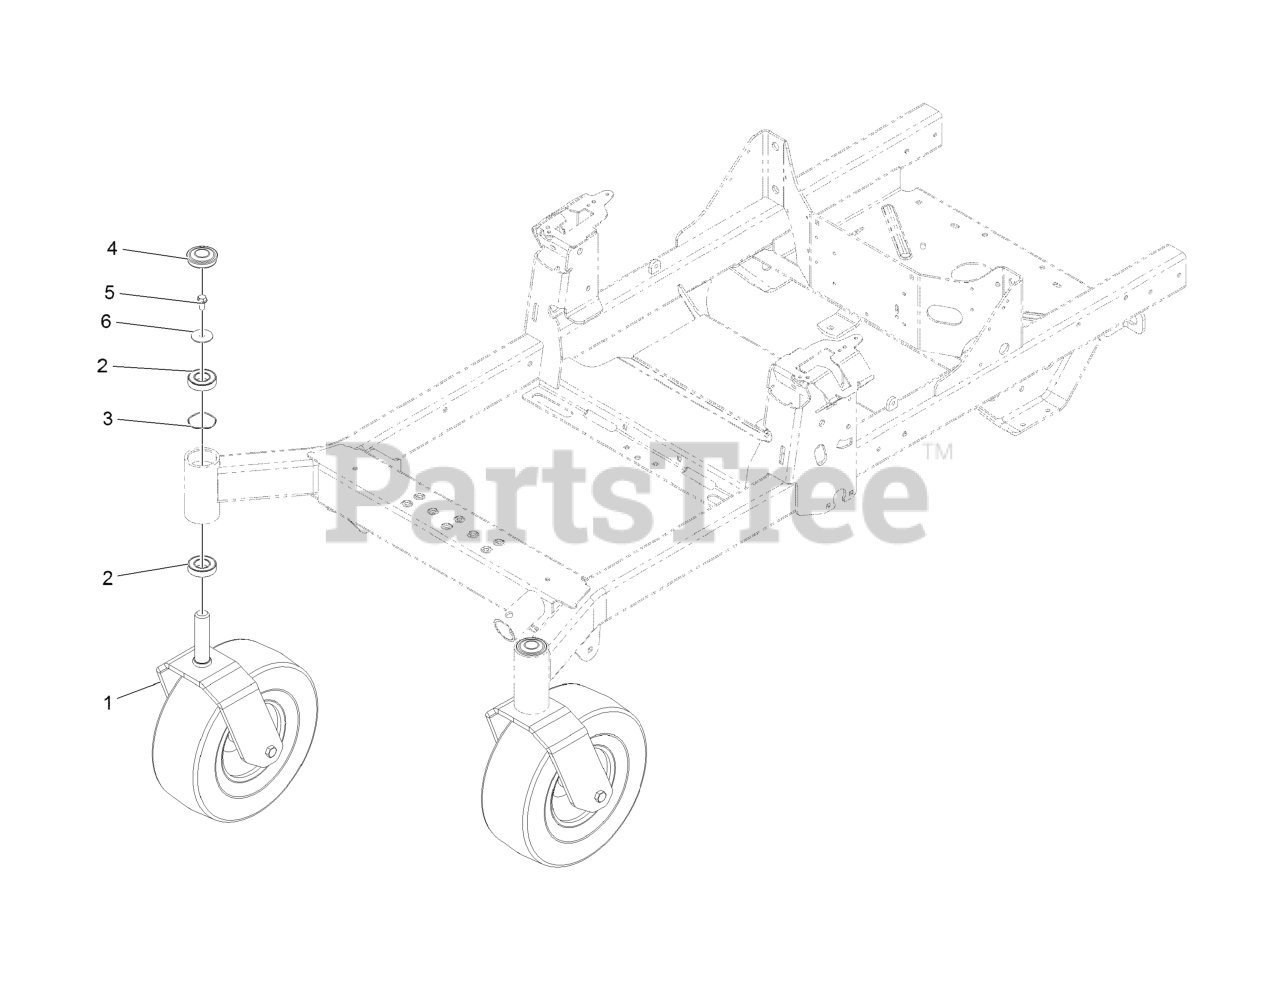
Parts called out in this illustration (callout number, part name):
1	ASM-Front Caster W/ Fork
2	BEARING-BALL
4	CAP-GREASE
5	SCREW-HHF
6	WASHER-FLAT
